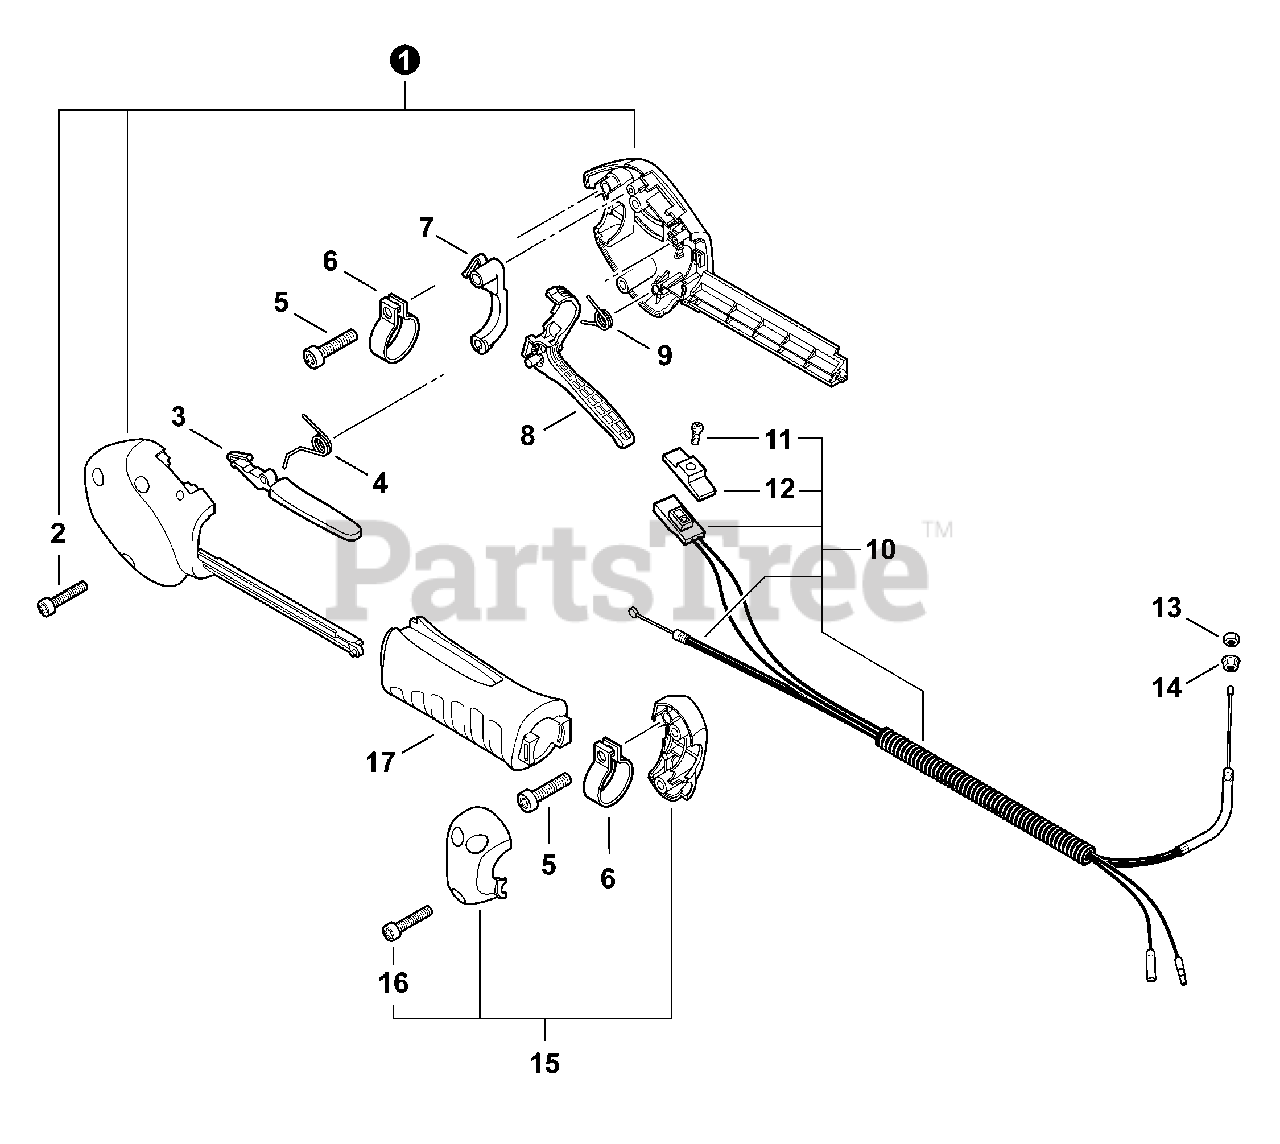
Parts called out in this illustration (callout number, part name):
1	HANDLE KIT, CONTROL
2	BOLT, TORX 4×20
3	LEVER, THROTTLE LOCKOUT
4	SPRING, TORSION
5	BOLT, TORX 5×20
7	LOCKOUT, THROTTLE
8	TRIGGER, THROTTLE
9	SPRING, TORSION
10	CABLE ASSY, CONTROL
11	SCREW 3×10
12	KNOB, SWITCH - ORANGE
14	NUT, FLANGE M6
15	FIXTURE SET, HANDLE
16	BOLT, TORX 4×20
17	GRIP, HANDLE
